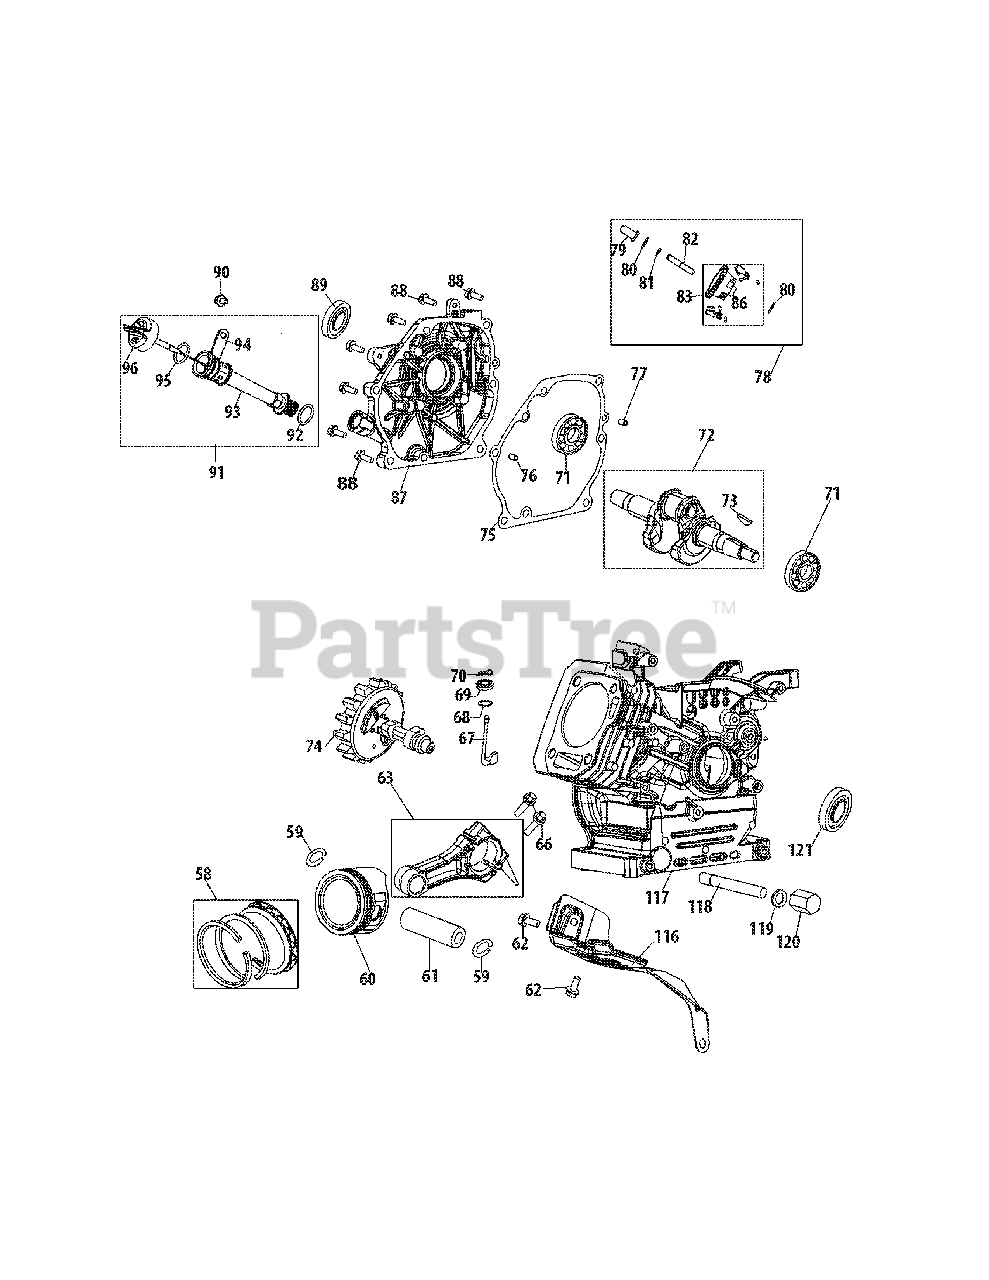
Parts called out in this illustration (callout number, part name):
58	Piston Ring Set
59	Circlip
60	Piston
61	Piston Pin
62	Bolt, M6×12
63	Connecting Rod Assembly
66	Connecting Rod Bolt
67	Governor Gear Shaft
68	O-Ring, 5.2×1.9
69	Oil Seal, 6×11×4
70	Cotter Pin
71	Bearing, 6205
72	Crankshaft
73	Woodruff Key
74	Camshaft
75	Gasket, Crankcase
76	Pin, 9×14
77	Pin, 7×14
78	Governor Gear
79	Governor Cup
80	Washer, 6.2×0.6×15
81	Retaining Ring
82	Governor Shaft
83	Governor Gear
86	Governor Gear
87	Crankcase Cover
88	Bolt, M8×32
89	Oil Seal, 25×41.25×6
90	Bolt, M6×16
91	Dipstick
92	O-Ring, 15.8×2.5
93	Dipstick Seat
95	O-Ring, 21×2.77
96	Dipstick
116	Shroud
117	Crankcase
118	Oil Drain Pipe
119	Washer, 10×1.5×16
120	Earth Bolt
121	Oil Seal, 25×41.25×6
